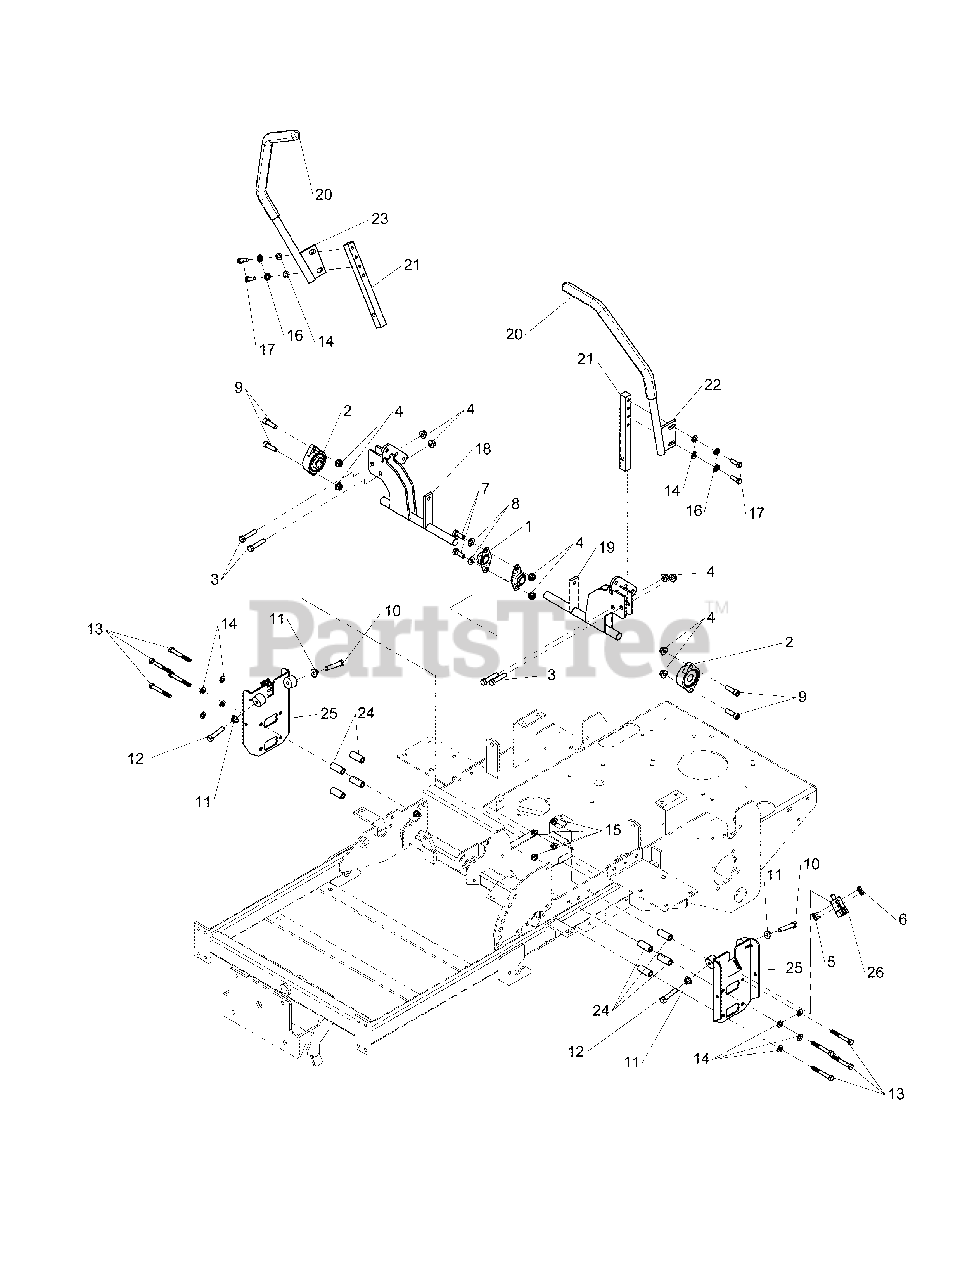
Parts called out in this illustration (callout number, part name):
1	BEARING, BRONZE FLANGE, 3/4"
2	BEARING, FLANGE
3	BOLT, 3/8-16 X 1-3/4" GD5
4	NUT, 3/8-16 HEX NYLOCK FLANGE
5	10-24 X .5 SCREW
6	NUT, HEX, #10-24
7	BOLT, 3/8-16 X 1" GD5
8	WASHER 3/8" SAE
9	3/8-16 x 1-1/4 SOCKET HD CAPSCR
10	BOLT, 5/16-18 X 2" GD 5 TFL
11	NUT, 5/16-18 HEX LG SERR FLG.
12	BOLT, 5/16-18 X 1.75" GD 5 TFL
13	BOLT, 5/16-18 X 2-1/2" GD5
14	WASHER, 5/16" SAE
15	NUT, 5/16-18 HEX NYLOCK FLANGE
16	WASHER, 5/16" LOCK
17	BOLT, 5/16-18 X 1" GD5
18	WELD, CONTROL SHAFT- RH
19	WELD, CONTROL SHAFT- LH
20	GRIP, FOAM, 3/4" ID, 16" LONG
21	MOUNT, CONTROL ARM - BLK
22	WELD, HANDLE MOTION CONTROL-LH
23	WELD, HANDLE MOTION CONTROL-RH
24	SPACER, .63 X .39 X 1.50
25	WELD, NEUTRAL PLATE
26	SWITCH, PLUNGER, N.O./N.C.
